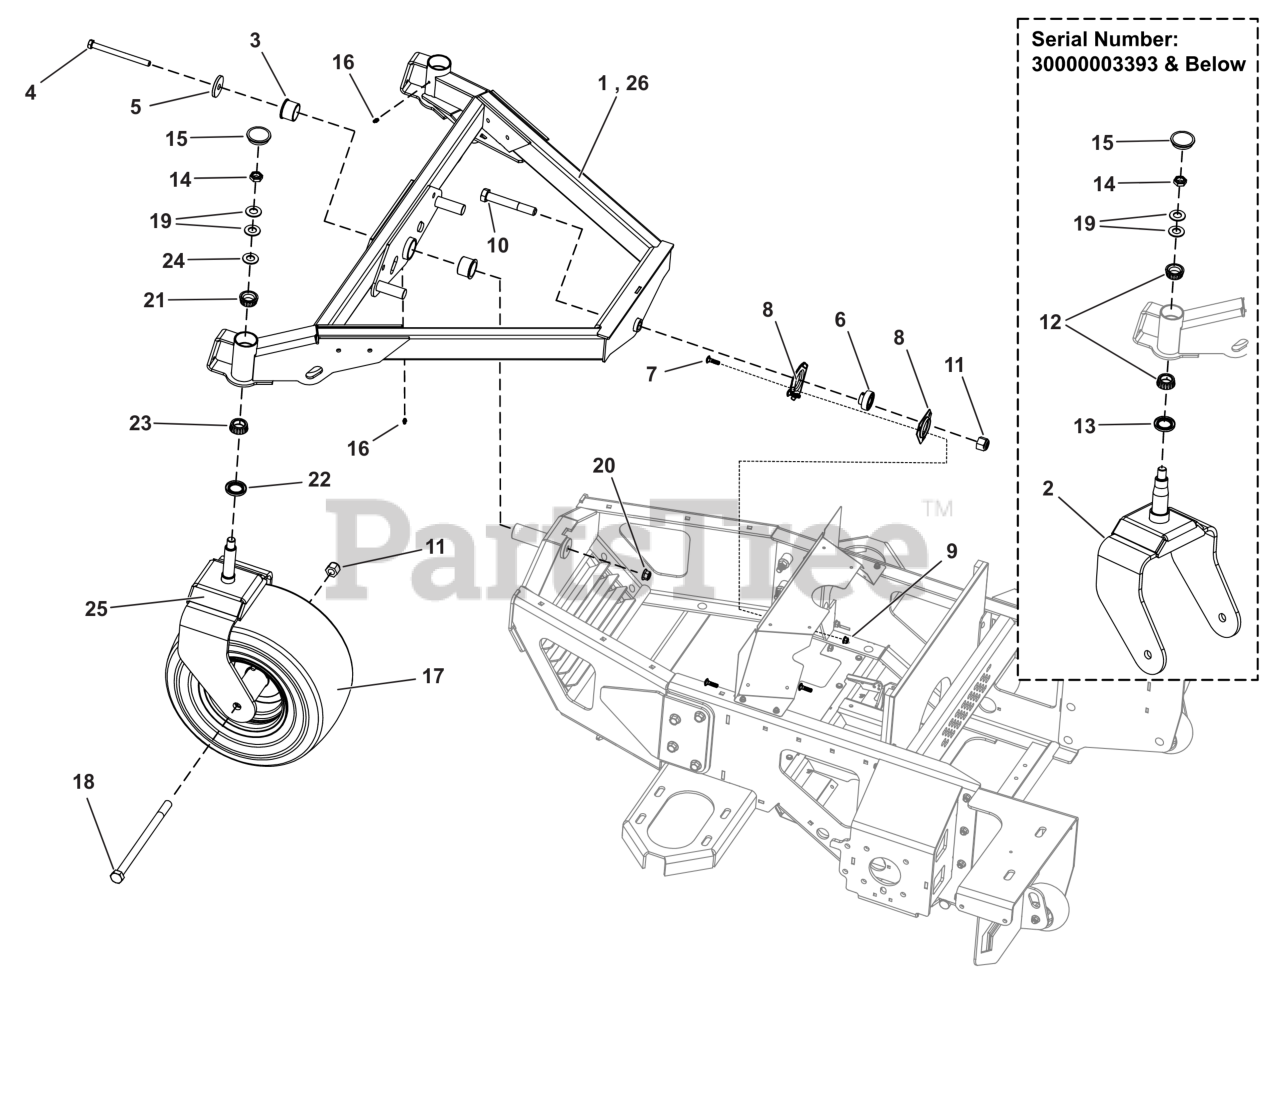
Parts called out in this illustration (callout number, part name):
1	WELD, FRONT AXLE
2	WELD, CASTER FORK
3	BUSHING, 1.500" I.D. X 1.50" LONG FLANGED
4	SCR-CAP, HEX .500"-13 X 6.000" SS188
5	WSHR-SS, FLT .516"X 2.13"X.250"
6	BEARING, SB204-12
7	BLT-RDHDSQNK, .3125"-18 X 1.250" SS188
8	47MM-3T-SS 3-BOLT SS FLANGETTE
9	NUT-HEX-NYLK, FLG .3125"-18 SS188
10	SCR-CAP, HEX .750"-10 X 5.000" SS188
11	NUT-HEX-NYLK, .750"-10 SS188
12	BRG, TPR 1.063" ID X .58" THK
13	SEAL, 1.375" SHAFT X 1.987" OD X 0.31 THK
14	NUT, 3/4-16, HEX JAM NYLON LOCK
15	CAP, GREASE, LOW PROFILE
16	ZERK, GREASE .250"-28 SS
17	WHEEL/TIRE 16 x 8.50 - 8 SMOOTH
18	SCR-CAP, HEX .750"-10 X 12.00" SS188
19	WASHER, BELLEVILLE - 1.500 X .755
20	NUT-HEX-NYLK, FLG .500"-13 SS188
21	BEARING, TAPER ROLLER, 1.1417
22	SEAL, 1.750 SHAFT X 2.254 OD X .359 THK
23	BEARING, TAPERED ROLLER 35MM BORE
23-1	BEARING & RACE, 1.3780 ID X 2.1654 OD
24	WASHER, 3/4 SAE
25	WELD, CASTER FORK
26	FRONT AXLE ASSEMBLY
